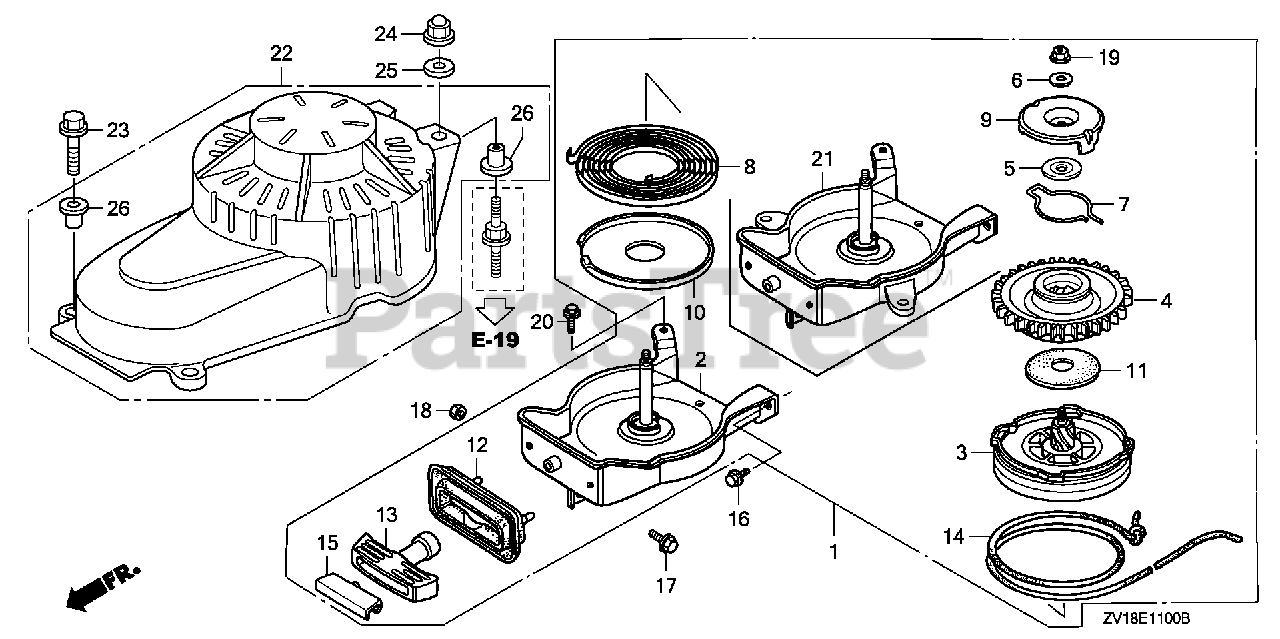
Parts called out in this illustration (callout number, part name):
1	STARTER ASSY., RECOIL *TBLACK* (BLACK)
2	CASE, RECOIL STARTER *TBLACK* (BLACK)
3	PULLEY, RECOIL STARTER
4	GEAR, STARTER
5	WASHER, THRUST
6	WASHER
7	SPRING, FRICTION
8	SPRING, STARTER RETURN
9	RETAINER, SPRING
10	HOLDER, SPRING
11	RUBBER, CUSHION
12	RUBBER, ENGINE COVER SEAL
13	GRIP, STARTER
14	ROPE, RECOIL STARTER (#5.5X79") (N/A: USE P/N 08555-ZG921-11)
16	BOLT, FLANGE (6X12) (CT200)
17	BOLT, FLANGE (6X16)
18	NUT, HEX. (6MM)
19	NUT, FLANGE (6MM)
20	BOLT, FLANGE (6X16)
21	CASE, RECOIL STARTER *TBLACK* (BLACK)
22	COVER, FLYWHEEL
23	BOLT, FLANGE (6X18)
24	NUT, FLANGE CAP (6MM)
25	WASHER (6.5X18)
26	COLLAR, RECOIL STARTER
